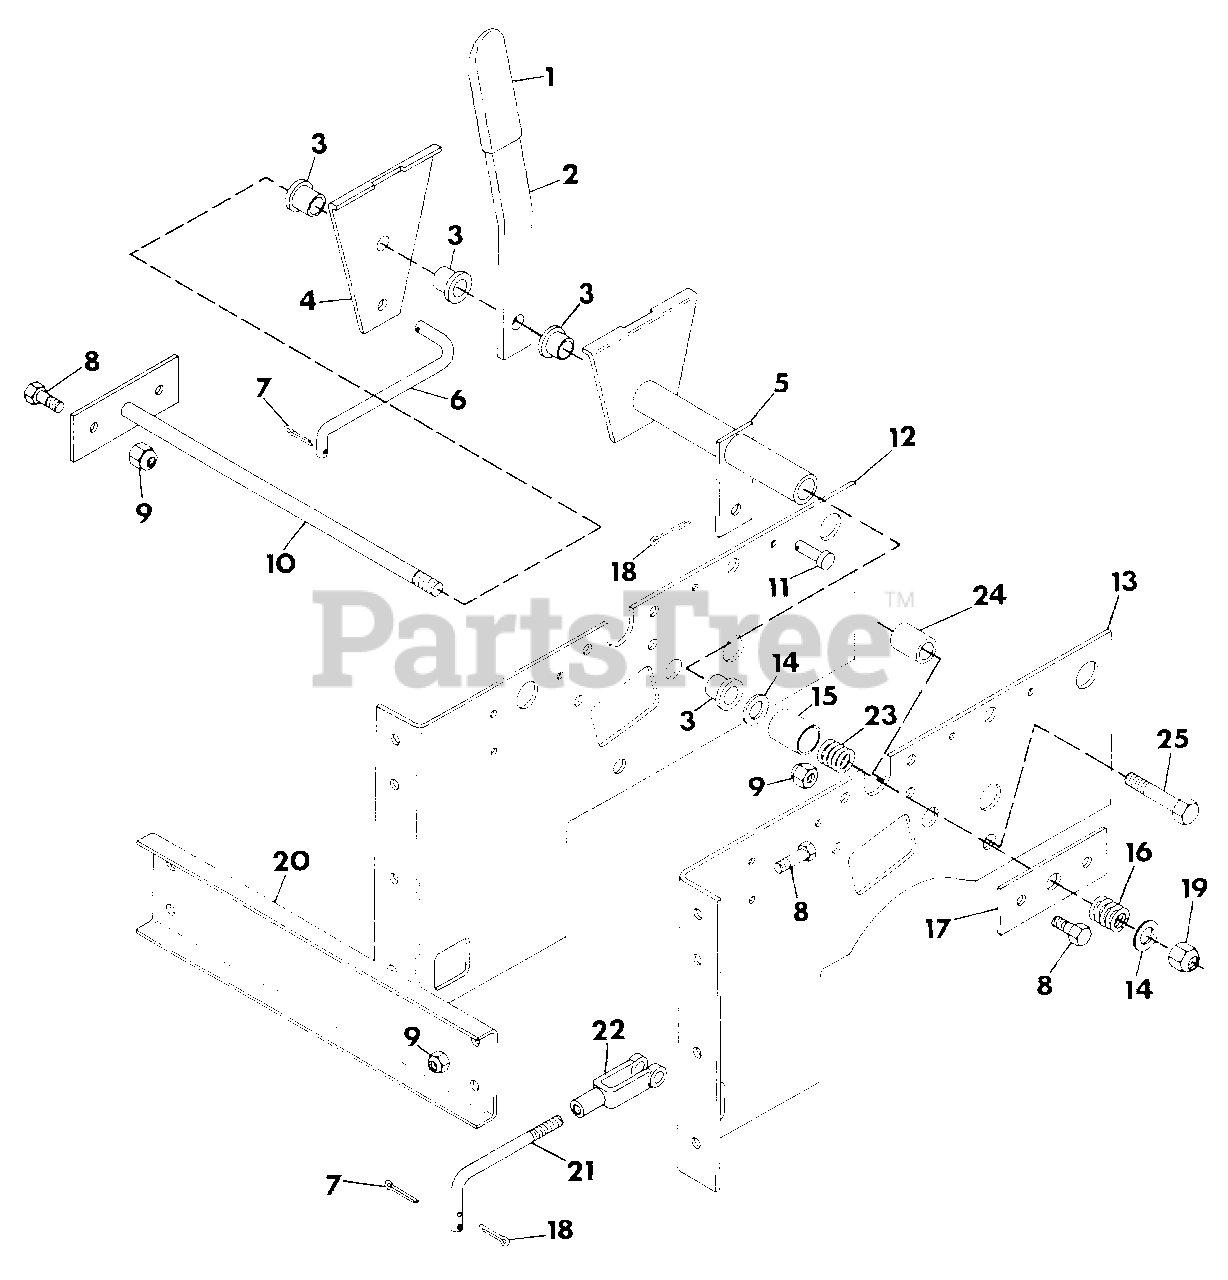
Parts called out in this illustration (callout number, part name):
1	GRIP, HANDLE
2	LEVER, SHIFTER
3	BUSHING, CABLE GUIDE PULLEY
4	WELDMENT, SHIFT LEVER R.H.
5	WELDMENT, SHIFT LEVER L.H.
6	ROD, GEAR SHIFT
7	PIN, COTTER HAIR
8	BOLT, HEX 3/8-16X.875
9	NUT, LOCK 3/8-16
10	WELDMENT, CROSS SHAFT
11	PIN, CLEVIS .375X.948
12	BRACKET, CONTROL MOUNT R.H.
13	BRACKET, CONTROL MOUNT L.H.
14	WASHER, FLAT .531X1.062X.095
15	SPACER, #2 SHAFT
16	SPRING, COMPRESSION 1.00X.78X338 LB/IN
17	PLATE, CROSS SHAFT
18	PIN, COTTER .09X.75
19	NUT, LOCK 1/2-13
20	BRACKET, HYDRAULIC TANK
21	ROD, GEAR SHIFT
22	CLEVIS, 3/8-24 ADJUSTABLE
23	SPRING, COMPRESSION 2.75X.625X34 RATE
24	BUSHING, .505X.750X1.00
25	BOLT, HEX 1/2-13X2.00
